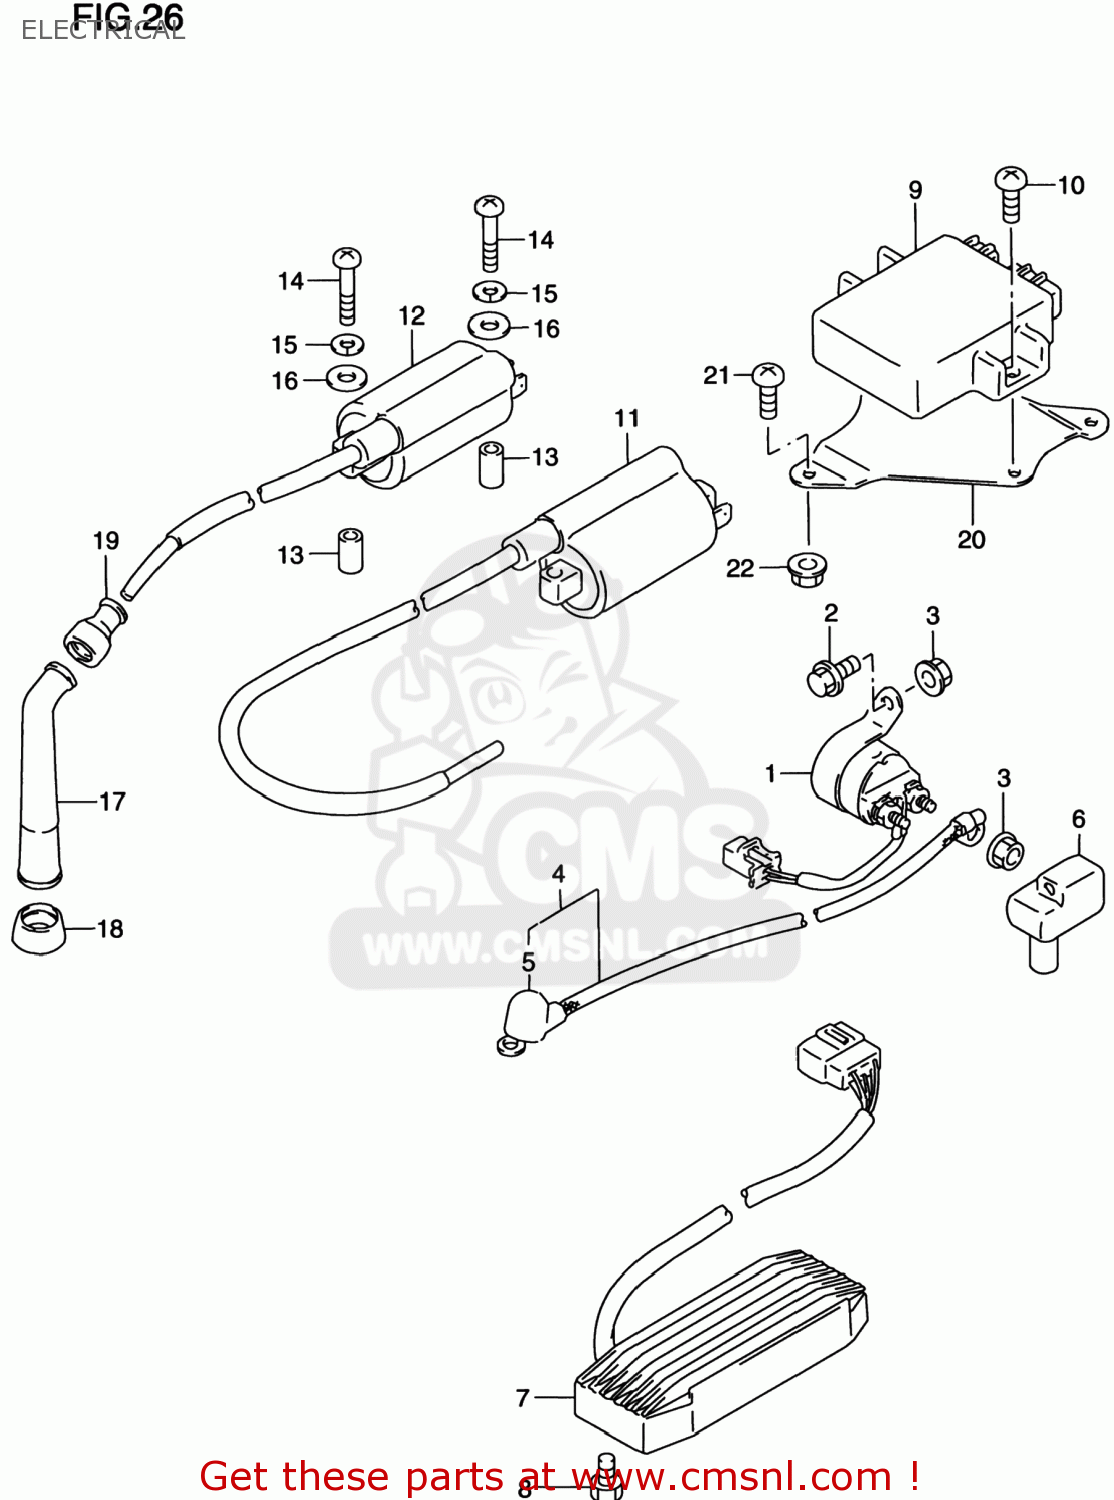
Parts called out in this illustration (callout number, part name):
1	RELAY ASSY,STARTING MOTOR
2	BOLT
3	NUT
4	WIRE,STARTER MOTOR LEAD
5	CAP,STARTER MOTOR LEAD
6	CAP,STARTER RELAY
7	RECTIFIER ASSY
8	BOLT
9	IGNITOR ASSY
10	SCREW 6X12
11	COIL ASSY,IGNITION
12	COIL ASSY,IGNITION
13	SPACER(6.4X10X19)
14	SCREW (5X38)
15	LOCK,WASHER
16	WASHER
17	CAP,SPARK PLUG
18	SEAL,SPARK PLUG CAP
19	SEAL,HIGH TENSION CORD
20	PLATE,IGNITOR FITING
21	BOLT
22	NUT
